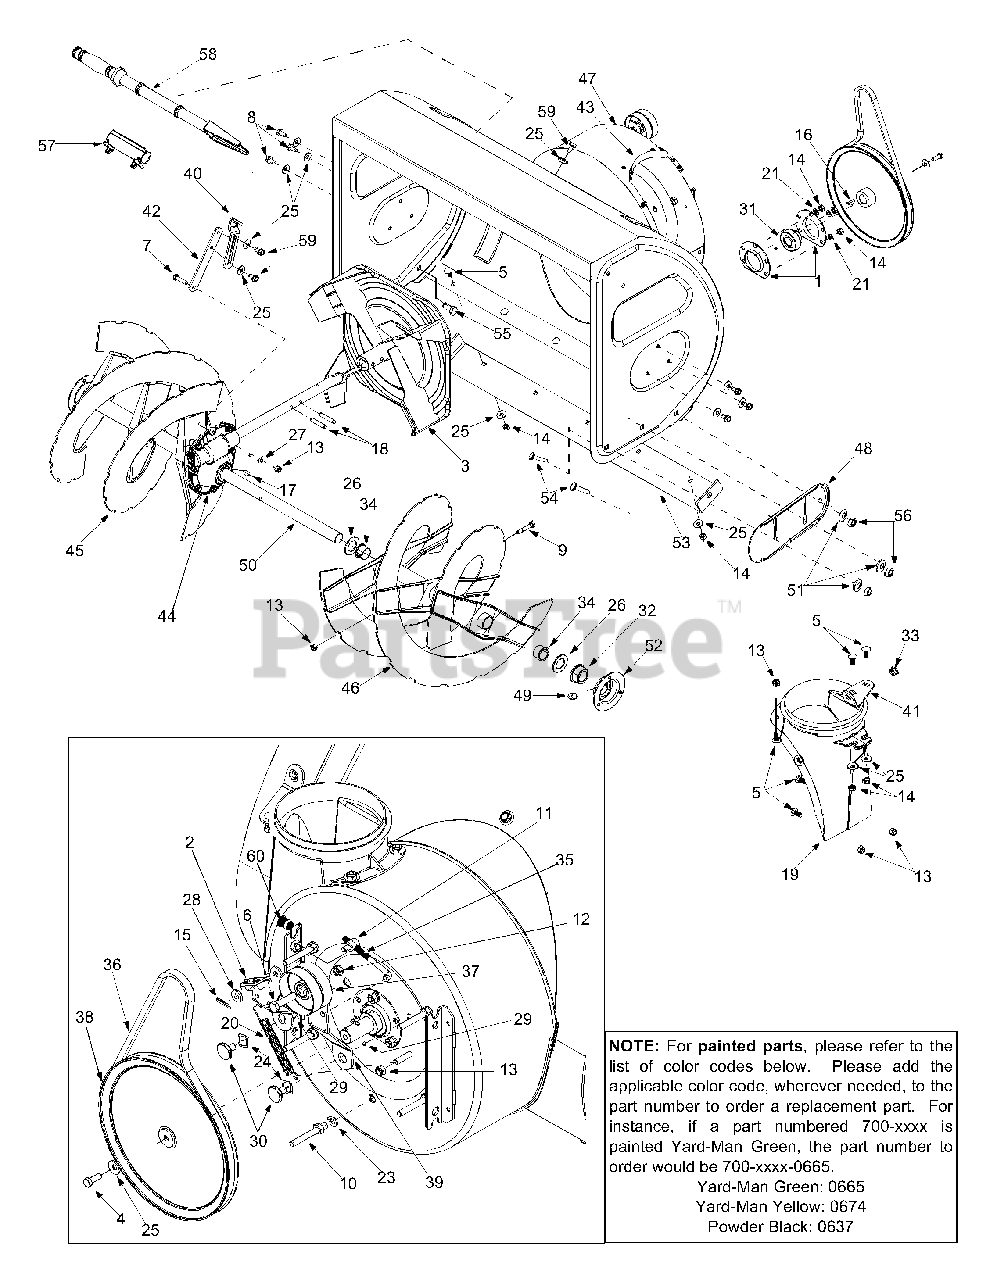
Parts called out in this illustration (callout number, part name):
1	Bearing Housing
2	Bracket Assembly: Auger Break
5	Carriage Bolt 5/16-18 x .750"
6	Hex Screw, Special 3/8-24 x 1.5"
7	Hex Screw 5/16-18 x 1.25"
8	AB Screw 5/16-12 x .75"
9	Shear Bolt 5/16-18 x 1.75"
11	Ferrule
12	Jam Nut 3/8-24
13	Flange Lock Nut 5/16-18
14	Hex Nut 5/16-18
15	Hairpin Clip
18	Spiral Pin
19	Chute Adapter
20	Extension Spring
21	Lock Washer
23	Lock Washer
24	Wave Washer
25	Beleville Washer
26	Flat Washer
27	Spring Washer
28	Flat Washer
30	Shoulder Screw
31	Self-Aligning Bearing
32	Flange Bearing w/ Flats
33	Plastic Bushing
34	Flange Bushing
35	Idler Rod: Auger
36	V-Belt
37	Flat Idler
38	Pulley
49	Lube Fitting
50	Spiral Axle
51	Bell Washer
52	Bearing Housing
54	Carriage Screw
55	Carriage Bolt
56	Hex Nut 3/8-16
57	Mount, Chute Clean-out Tool
58	Chute Clean-Out Tool
59	Screw, 5/16-18 x .75
60	Insert Nut, 3/8-16
